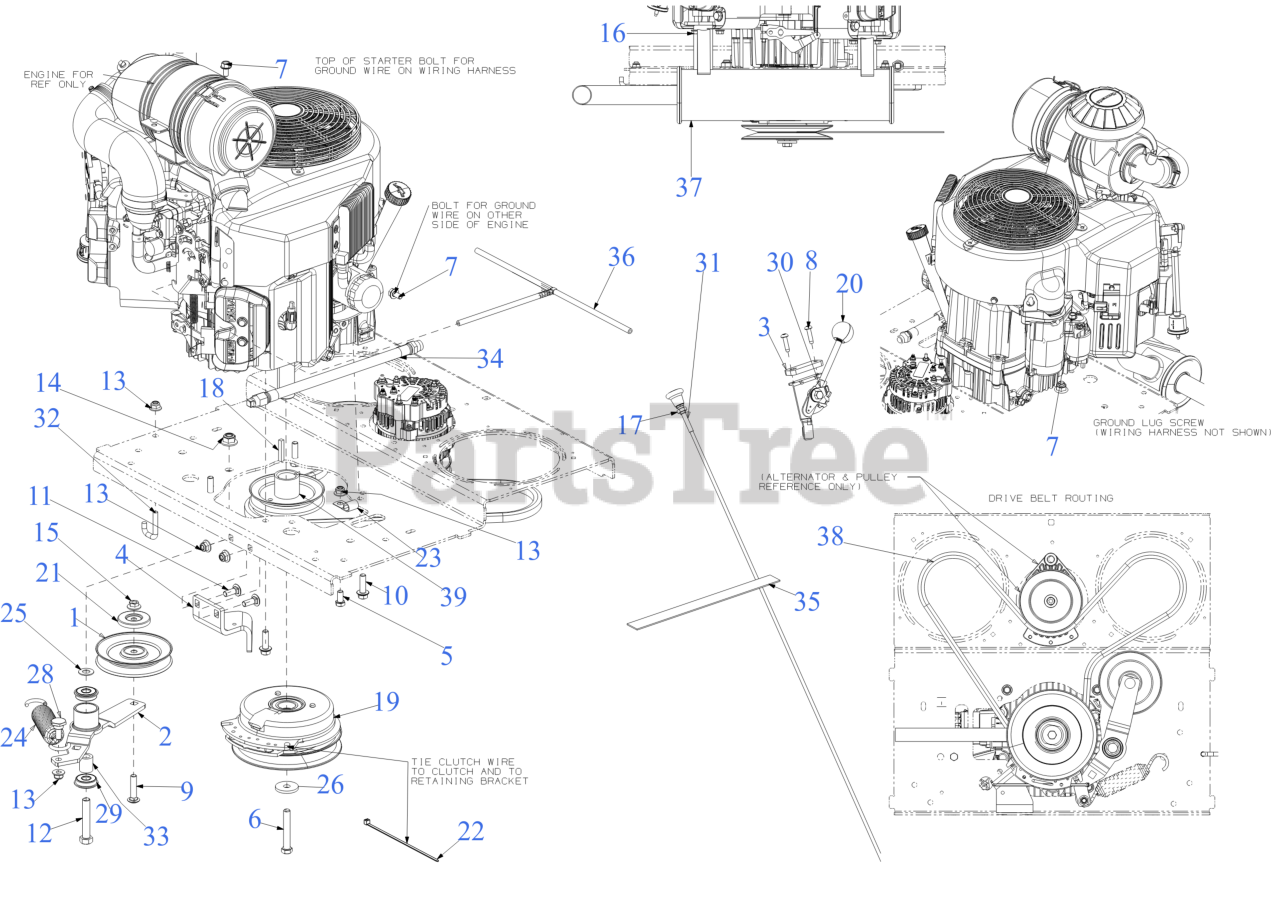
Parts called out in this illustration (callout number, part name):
1	V-IDLER PULLEY
2	IDLER ARM BRACKET
4	CLUTCH RETAINER BRACKET
5	HEX SCREW 3/8-16 x .75
6	SCREW 7/16-20:2.75 GR5
7	SCREW M8 x 1.25 x 16MM GR8.8
8	SCREW 1/4-20 x 1.0
9	CARRIAGE BOLT 3/8-16 x 1.75 GR5
10	SCREW 3/8-16 x 1.25 GR5
11	CARRIAGE BOLT 3/8-16 x 1.00 GR5
12	SCREW 1/2-13 x 2.75 GR5
15	FLANGE LOCK NUT
16	HEX FLANGE NUT
17	HEX JAM NUT 3/8X24
18	SQUARE KEY 1/4 x 1.50
19	ELECTRIC PTO CLUTCH
21	PULLEY CAP
22	7" CABLE TIE
23	J TYPE CLIP
24	EXTENSION SPRING W/HOOK
25	FLAT WASHER .510 x .995
26	FLAT WASHER .45 x 1.5 x .172 HT
28	SHOULDER SCREW .625 x .302 x 3/8-16
29	ROLLER BEARING .5X1.37X.44
30	THROTTLE CABLE 59"
31	CHOKE CABLE
32	ROD SPRING HOOK
33	SPACER 0.51 x 0.88 x 1.00
34	OIL DRAIN HOSE
35	HEAT SHIELD 24"
36	ROLLOVER VENT HOSE ASSEMBLY
37	MUFFLER - KAWASAKI 1000
38	BELT 65.5"
39	PULLEY - PUMP DRIVE
